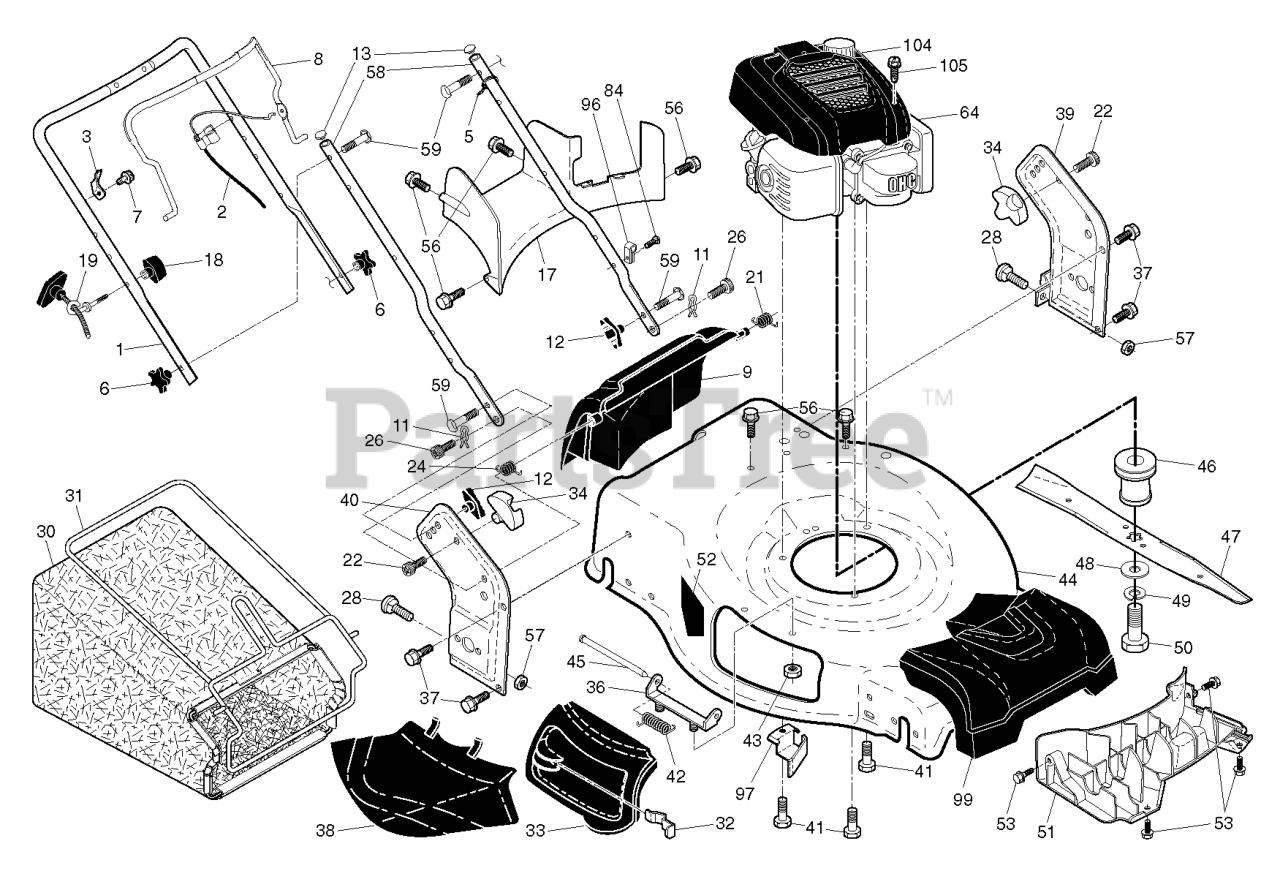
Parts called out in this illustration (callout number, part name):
1	HANDLE.UPPER.3.POS.BS.AW2.GREY
2	CABLE.MZR.50.SNAP-IN
3	BRACKET.UPSTOP.RT
5	TIE GUIDE
6	KNOB.HANDLE.PLASTIC.STAR.BLACK
8	BAIL.OVER.MOLD.ERGO.MZR.ORANGE
9	DOOR.REAR.ASM.22+.HUSQ.F/RG.CE
11	COTTER.HAIRPIN.DOOR/HANDLE.PIV
12	KNOB, DEFLECTOR
13	PLUG.PLASTIC.7/8".14-20.GAUGE
17	BAFFLE.REAR.22+RGD.AWD.PLASTIC
18	T-KNOB.NEW ROPE GUIDE
19	GUIDE.ROPE.BLK.ZINC.CHROM
21	SPRING.LH.BLACK
22	SCREW.PAN.HEAD.#10
24	SPRING.RH.GRAY
26	SCREW,DOOR/HANDLE.PIVOT
28	BOLT.CARRIAGE.LN.5/16-18X.5/8
30	GBAG.BA85028ER.GRY/ORG
31	FRAME.GBAG.22+.BLK
32	LATCH.DOOR.ZINC
33	DOOR.MULCH.22 PLUS.HUSQ.GREY
34	BRACKET.GRASSBAG.ATTACHING.BLK
36	BRACKET.ASM.HINGE.21.FWGD.
37	BOLT.5/16HEX.WHS.HD
38	DEFLECTOR.CLIPPING.22.BLACK
39	BRACKET.ASM.HANDLE.LT.22+.GREY
40	BRACKET.ASM.HANDLE.RT.22+.GREY
41	BOLT 3/8-16X1-1/8
42	SPRING.TORSION
43	NUT.HEX.FLANGE.1/4
44	KIT.HSG.22+RGD.MC.WO.668.CE
45	ROD.HINGE.21
46	ADAPTER.BLADE.25MM.3MPH
47	BLADE 22 4-N-1 2PIN 5STAR BLK
48	WASHER,HARDEN
49	LOCKWASHER
50	SCREW, HEX HD 3/8-24 X 1-3/8
51	BAFFLE.FRONT.22+PLASTIC.(2 2)
52	DECAL.INTERNATIONL.CUTFINGER
53	SCREW.HI-LO.5/16 X.75
56	SCREW.HX.13X.750
57	NUT.FLANGE.5/16
58	HANDLE.LOWER.22+.BT.GRAY
59	BOLT, HANDLE 5/16-18X1.75
84	FASTENER.PUSH.O.250X0.783
96	CLIP.CABLE.BLK
97	BRACKET.BELT.GUIDE.22+.BZP
99	COVER.ASM.FRONT.SHROUD.HUSQ.
104	SHROUD.ASM.HONDA.HUSQVARNA
105	SCREW.SHROUD.HONDA
